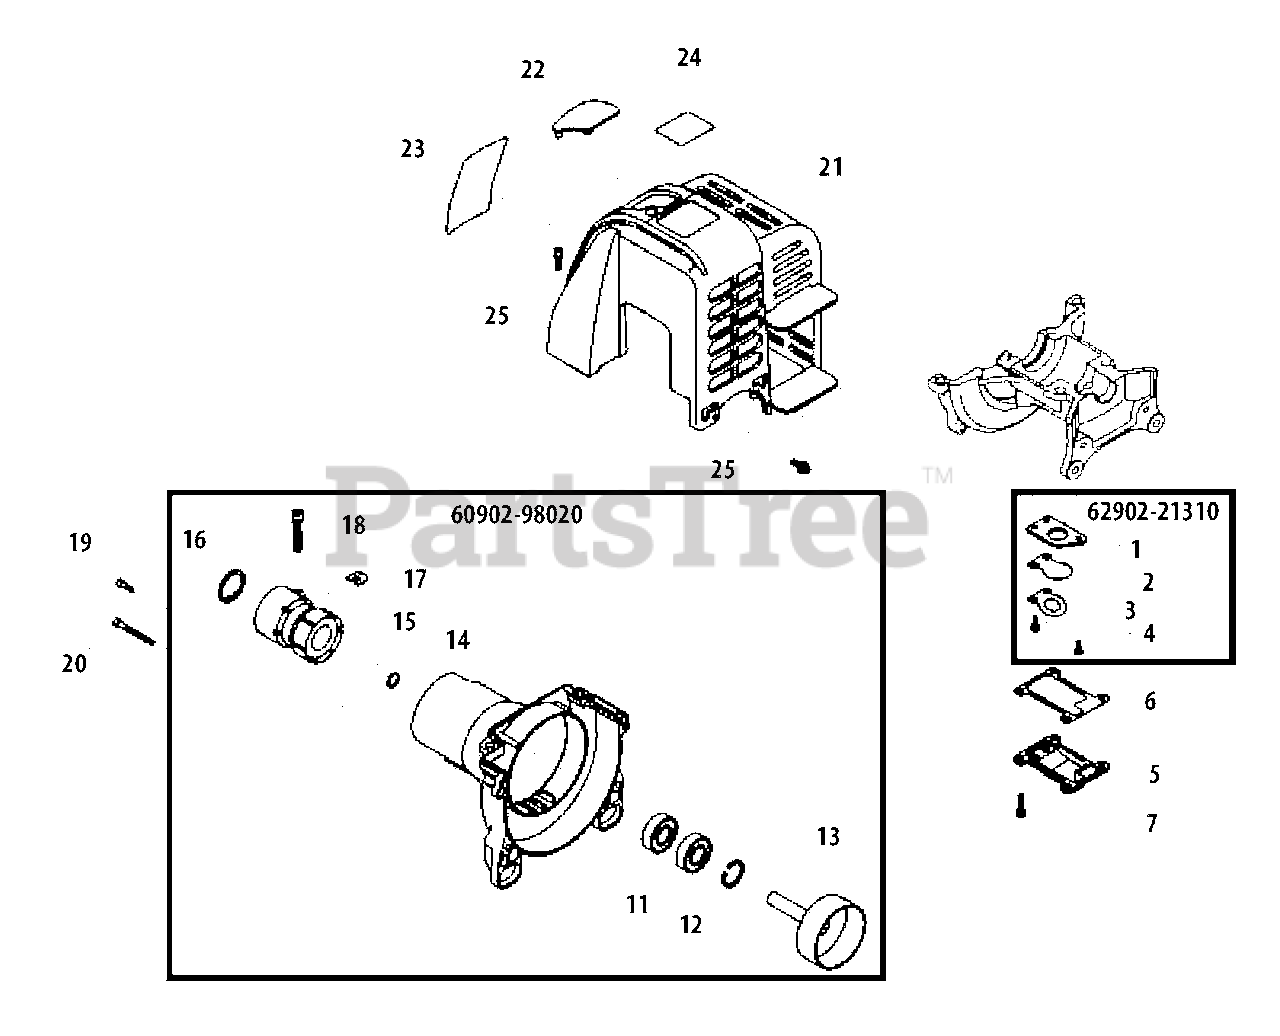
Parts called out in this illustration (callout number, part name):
1	PLATE, REED BACKING
2	VALVE, REED
3	STOP, REED VALVE
4	SCREW - 3X10
5	COVER, REED VALVE
6	GASKET, REED VALVE
7	SCREW - 4X12
11	BEARING, BALL - 6000
12	RING, RETAINING - 26
13	DRUM, CLUTCH
14	RING, RETAINING
15	CLAMP, MAIN PIPE
16	RING, RETAINING - 40
17	SHIM
18	SCREW - 5X22
19	SCREW - 5X16
20	SCREW - 5X35
21	COVER, ENGINE
22	GROMMET
23	LABEL - C4
24	LABEL - TRADE
25	SCREW - 4X16
60902-98020	FAN CASE ASSY
62902-21310	REED VALVE ASSY
